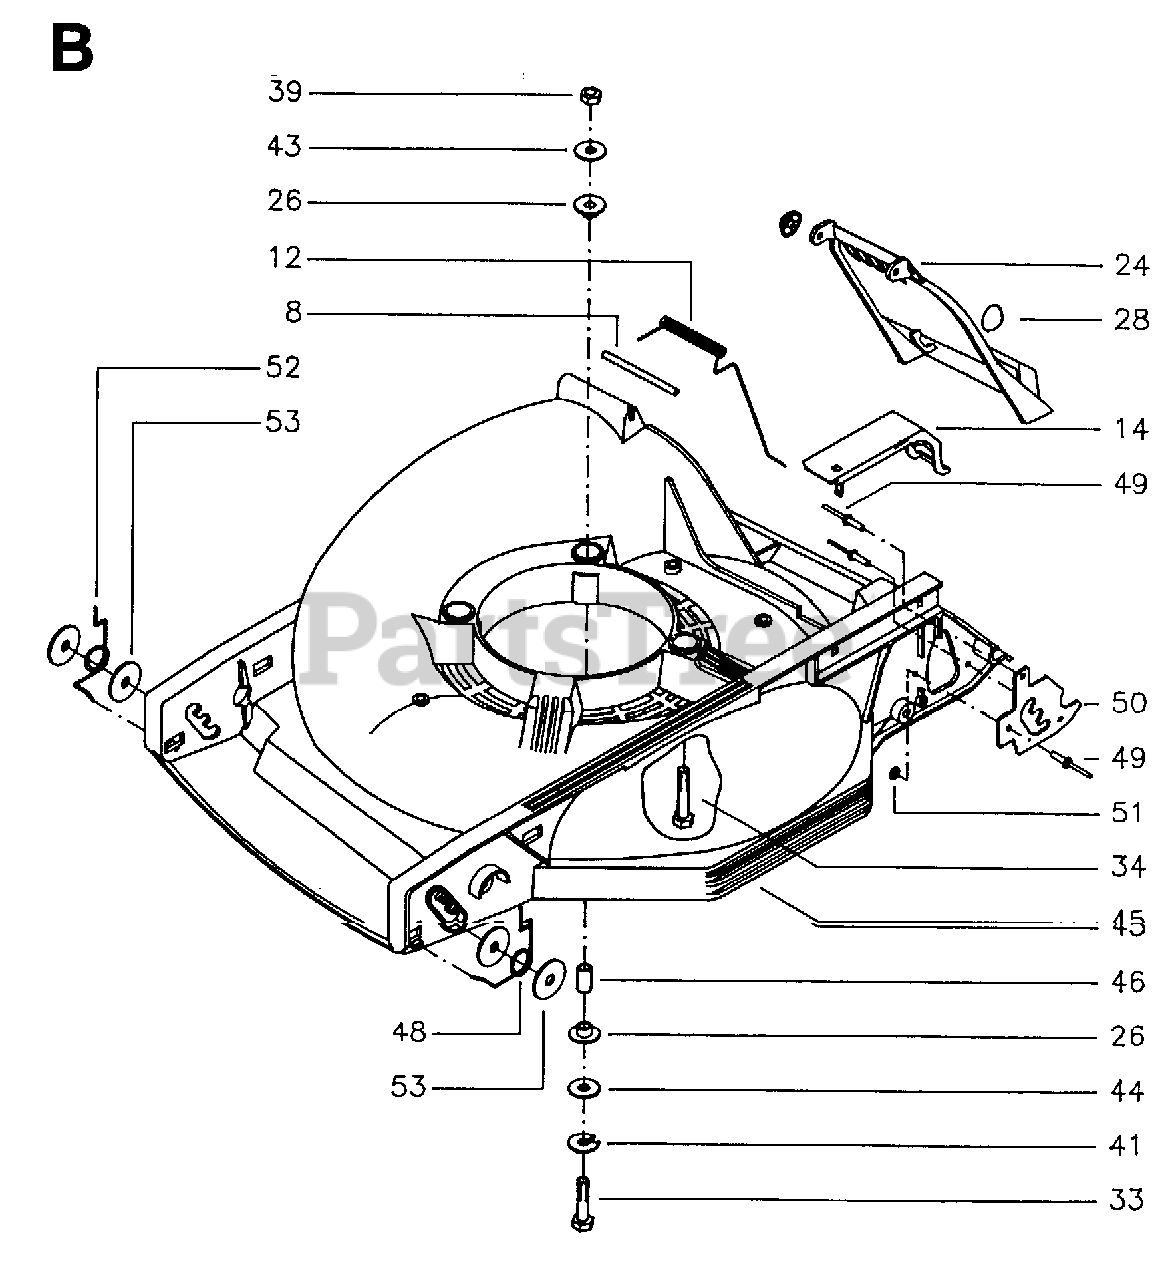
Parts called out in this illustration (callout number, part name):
39	LOCKNUT M8
41	SPRING WASHER
51	WASHER
